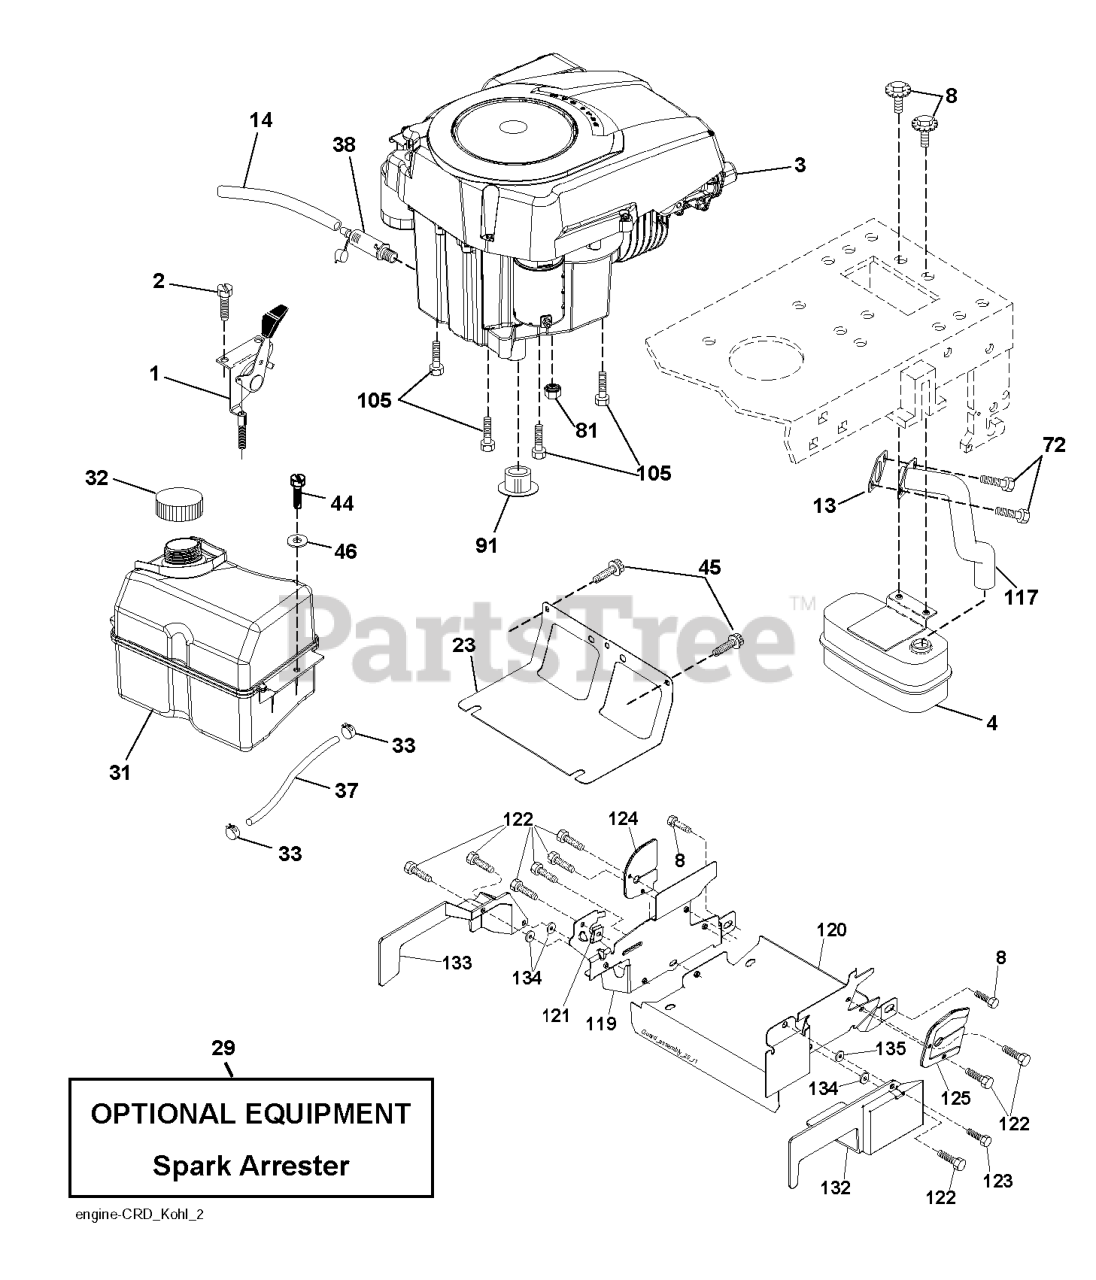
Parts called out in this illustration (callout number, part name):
1	CONTROL.TH/CK.C.
2	SCREW.#10 X 0.750.BOS
4	MUFFLER.SINGLE.CYL.KOHL/B&S
8	BOLT.5/16-18UNCX3/4 W/SEMS.BLK
13	GASKET.EXHAUST.KOHLER
14	TUBE, DRAIN OIL ASM.
23	SHIELD.BROWNING.DBR.GUARD
29	KIT.SPARK ARRESTOR 794945 B&S
31	RP TANK FUEL FRT 1.5 GAL
32	FUEL CAP
33	HOSE CLAMP
37	LINE.FUEL.20
38	PLUG DRAIN OIL EASY
44	SCREW HEXWSHR 1/4-20X3/4
45	SCREW, 3/8-16X3/4
72	SCREW.SOCKET HD.5/16-1
81	NUT
91	BUSHING.1.375OD
105	SCREW 3/8-16X1
117	RP.TUBE.EXHAUST.KOHL.COURAGE
119	LENKRAD
120	GUARD 532199767
122	SCREW.1/4-20X5/8
123	SCREW, 5/16-18 X 1/2
132	SHIELD RIGHT
133	SHIELD LEFT
134	PALNUT 1/4
135	WASHER 5/16"
